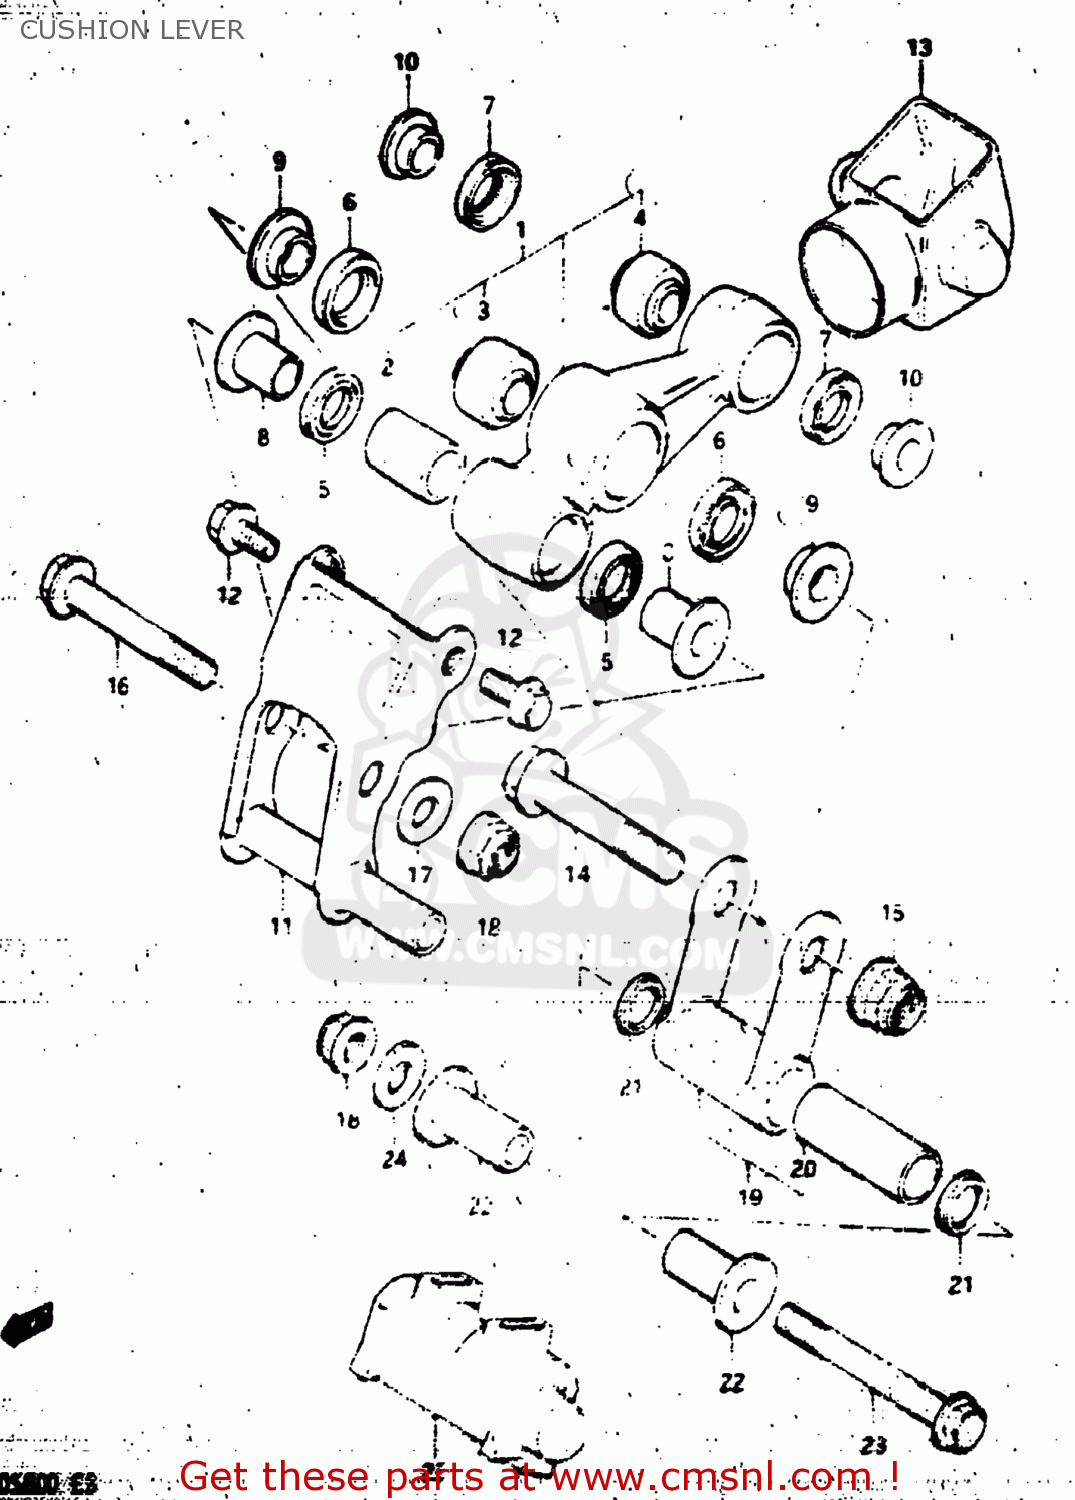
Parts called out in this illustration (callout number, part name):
1	LEVER SET,REAR CUSHION
2	BUSHING,REAR CUSHION LEVER
3	BEARING(12X26X16)
4	BEARING(10X24X15)
5	DUST SEAL,RR CUSHION LEVER FR
6	DUST SEAL,RR CUSHION LEVER CTR
7	DUST SEAL,RR CUSHION LEVER RR
8	SPACER,RR CUSHION LEVER FR
9	SPACER
10	SPACER
11	HOLDER,RR CUSHION LEVER
12	BOLT,REAR CUSHION LEVER
13	BOOT,RR
14	BOLT(12X55)
15	NUT 12MM
16	BOLT,REAR CUSHION LEVER
17	WASHER
18	NUT
19	LOD SET,RR CUSHION
20	BUSHING,LOD LWR(15X20X54)
21	DUST SEAL,LEVER CUSHION UNIT
22	SPACER,RR CUSHION ROD LWR
23	BOLT,RR CUSHION ROD LWR
24	WASHER
25	BOOT,LWR
